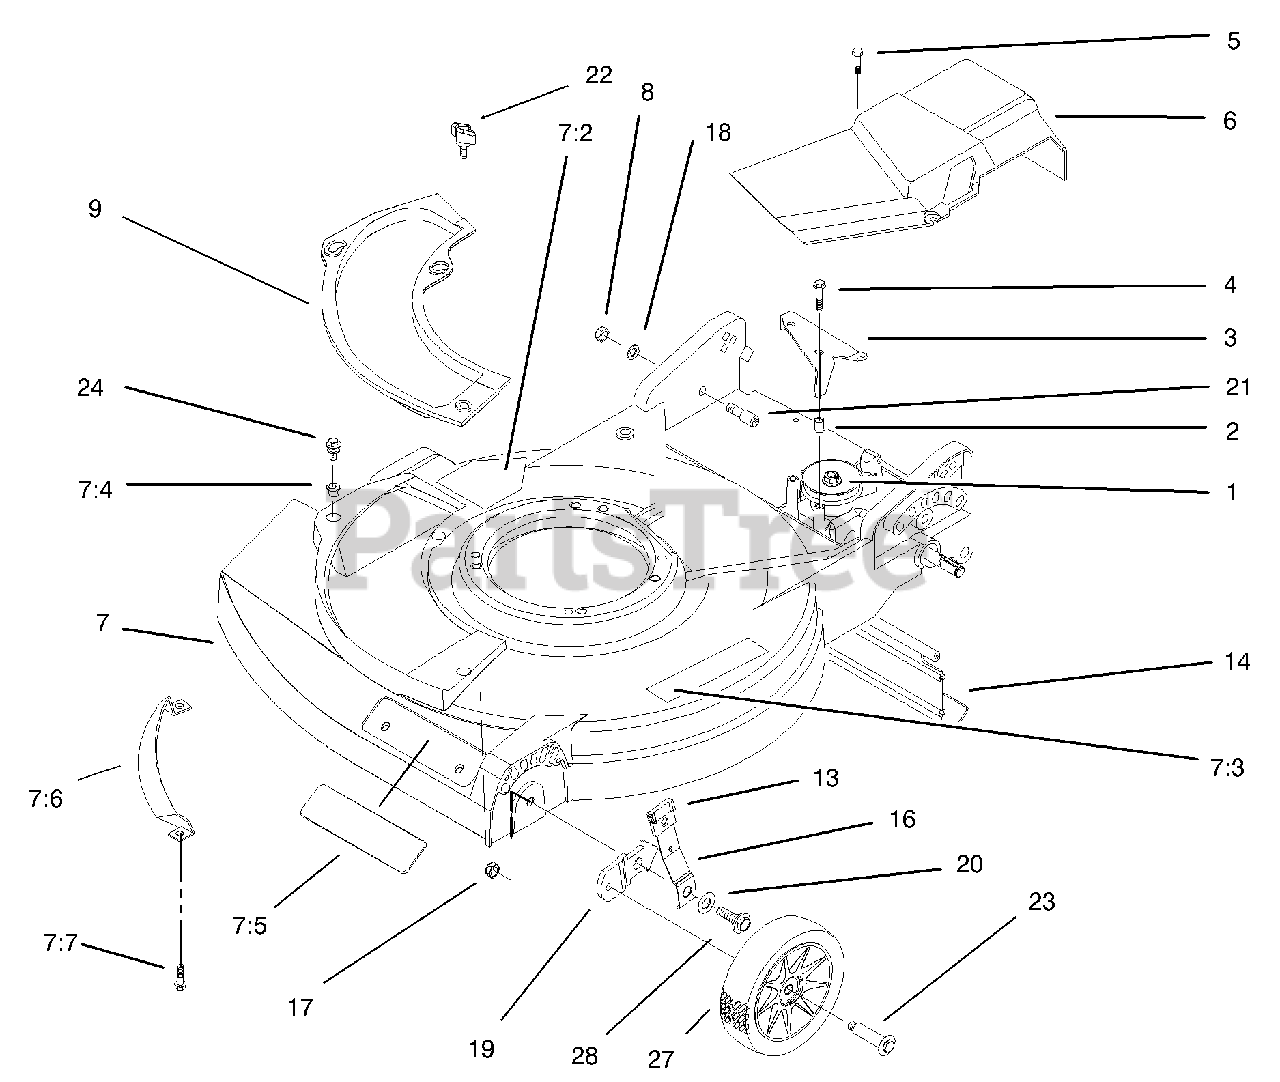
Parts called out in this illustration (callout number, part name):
1	GEAR CASE ASM
3	BRACKET-ACTUATOR
4	SCREW-HWH
6	COVER - DRIVE
7	HOUSING-ASM
7:2	DECAL-DANGER
7:3	DECAL-WARNING
7:4	NUT-CLIP
7:5	DECAL-DECK
7:6	BAR-TOE
7:7	SCREW-HWH
9	PLATE-OPENING, CHUTE
13	KNOB-LEVER, HEIGHT ADJUSTMENT
14	SHIELD - TRAILING
16	FRONT SPRING ARM ASM
17	NUT-LOCK, NI
19	BRACKET-HEIGHT ADJUSTMENT, WHEEL
20	WASHER-BELLEVILLE
21	SCREW-TORX
24	SCREW-SEMS
27	WHEEL/TIRE ASM
28	BOLT-SHOULDER
